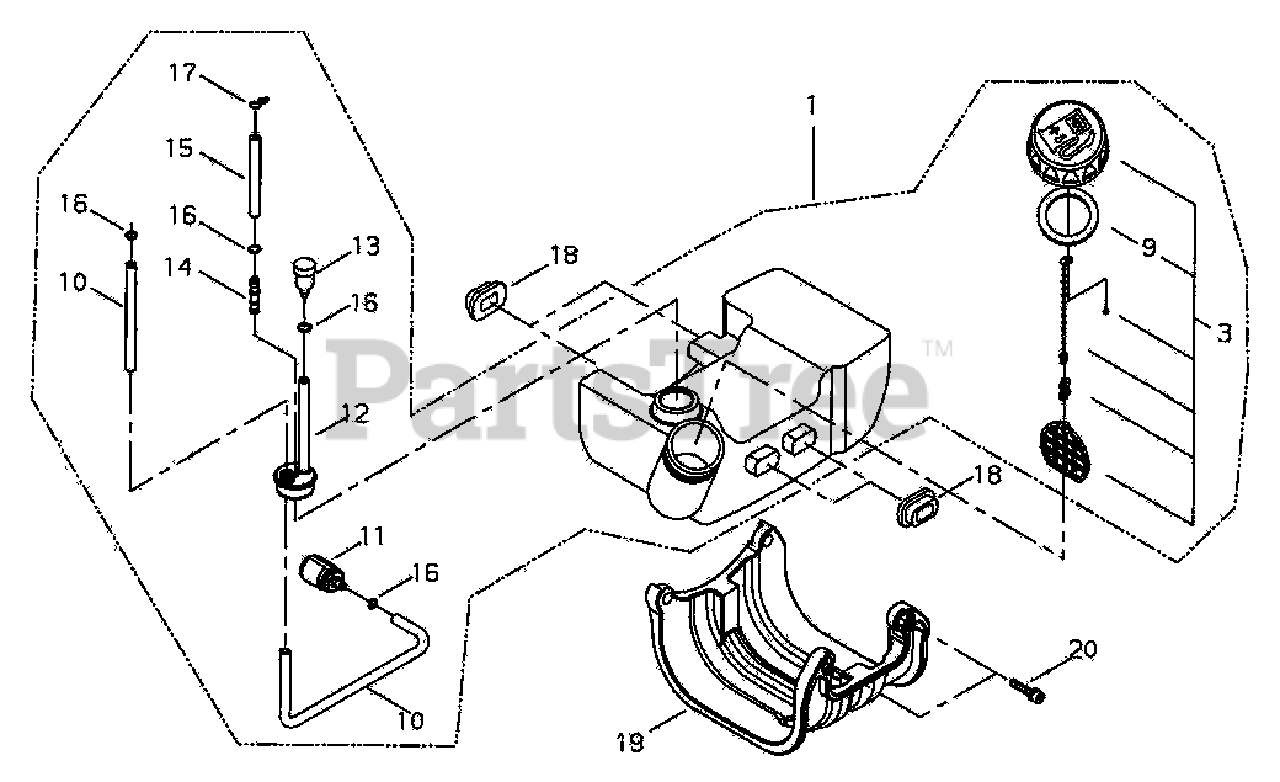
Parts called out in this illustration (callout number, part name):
1	TANK ASSY, FUEL
3	CAP ASSY, FUEL
9	GASKET, FUEL CAP
10	PIPE, FUEL 3.3×6×160
11	FILTER, FUEL 125-528
12	GROMMET
13	VENT ASSY
14	CONNECTOR, PIPE
15	PIPE
16	CLIP Ø6
17	CLIP, SPRING Ø5.2
18	CUSHION, FUEL TANK
19	GUARD, PLASTIC FUEL TANK
20	BOLT M5×20
